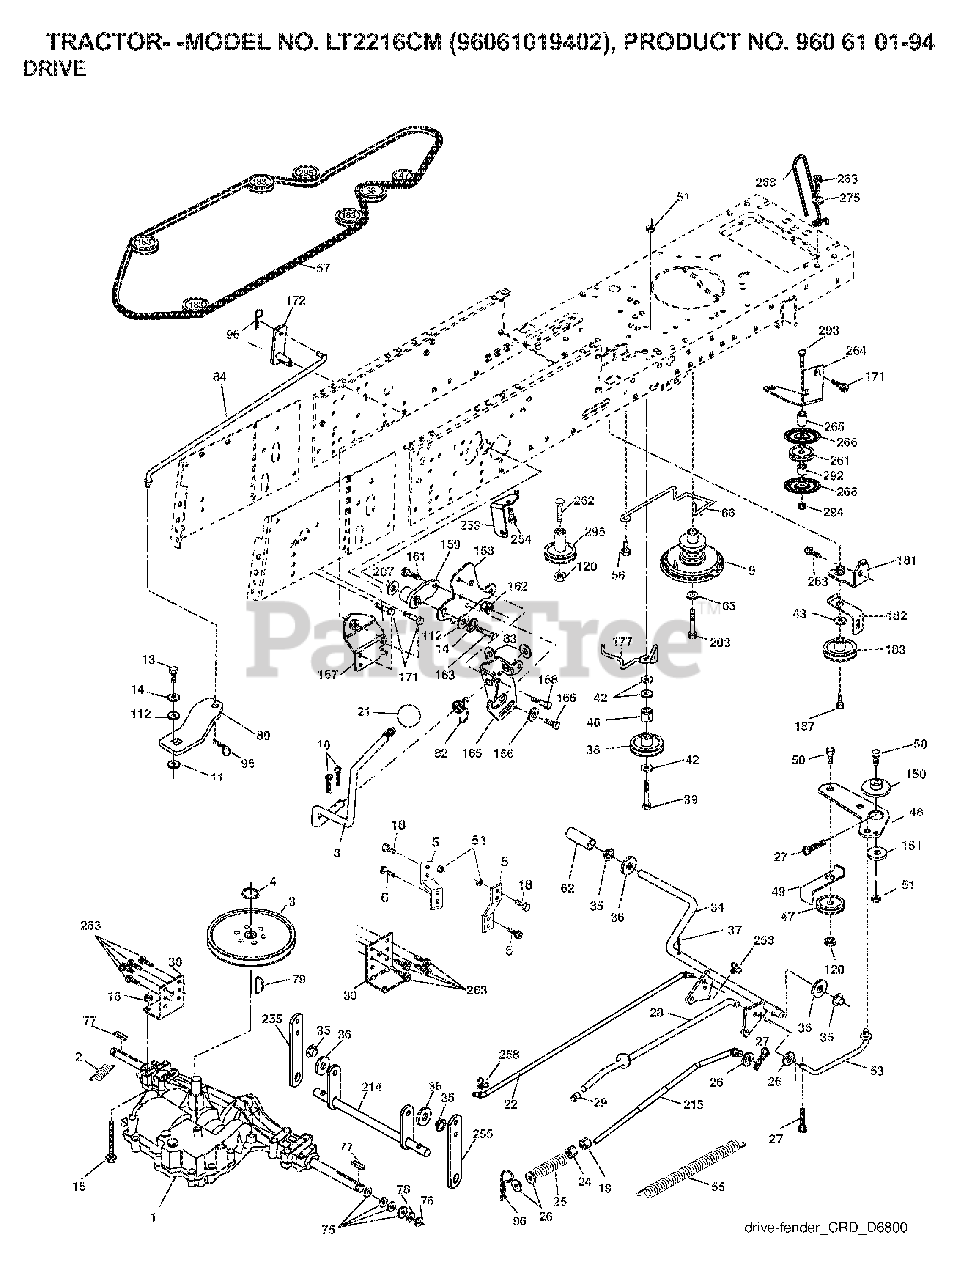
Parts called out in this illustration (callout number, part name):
2	SPRING,BRAKE RETURN
4	RETAINING RING LT
5	STRAP TORQUE
6	SCREW 5/16"
8	ROD SHIFT FENDER ADJUST LT
10	PIN COTTER
11	WASH-SHFT PLT LT
13	BOLT 1/4-28X3/4
14	LOCKWASHER
15	BOLT HEX 5/16-18 GR 5
16	NUT.71038.31-18.HEX.NYLOCK
19	NUT
21	KNOB.DUCKHEAD.1/2
24	NUT
25	SPRING ROD LT
27	COTTER PIN
28	ROD, PARKING BRAKE
29	PLUNGER CAP
30	BRKT, MOUNT TRNSAXLE
34	SHAFT, FOOT PEDAL
35	BEARING.NYLON
36	WASHER LT
37	DRIVE PIN
38	PULLEY.FLAT
42	WASHER
47	IDLER PULLEY
48	BELLCRANK, CLUTCH
49	RETAIN BELT
50	BOLT.3/8-16X1.50
51	LOCKNUT
53	LINK.CLUTCH.7.66.2005
55	SPRING, RETURN LT
56	SCREW.3/8-16
62	PEDAL COVER T
65	LOCKWASHER
66	KEEPER BELT ENGINE
76	E-RING LT
77	SQUARE KEY
80	ARM SHIFT
82	SHIFT SPRING
83	WASHER
96	RETAINER M
112	WASHER LT
120	NUT LOCK FLG 3/8-16 UNC
150	BUSHING.BELLCRANK.GRD.DR
151	WASHER 12/32X2X10GA
156	WASHER.SRRTD.5/16
158	BRACKET
159	HUB.SHIFT
161	BOLT
162	NUT.CROWNLOCK.1/4
165	RP BRACKET
167	BRACKET
168	BOLT.SHOULDER.5/16-18X
187	BOLT.5/16-18X1.25
207	WASHER NYL
254	SCREW 3/8-16X1
258	CLIP RETAINER
261	FLAT IDLER PULLEY
263	SCREW, 3/8-16X3/4
275	WASHER
294	NUT, HEX 3/8-16
295	PULLEY IDLER COMPOSITE
